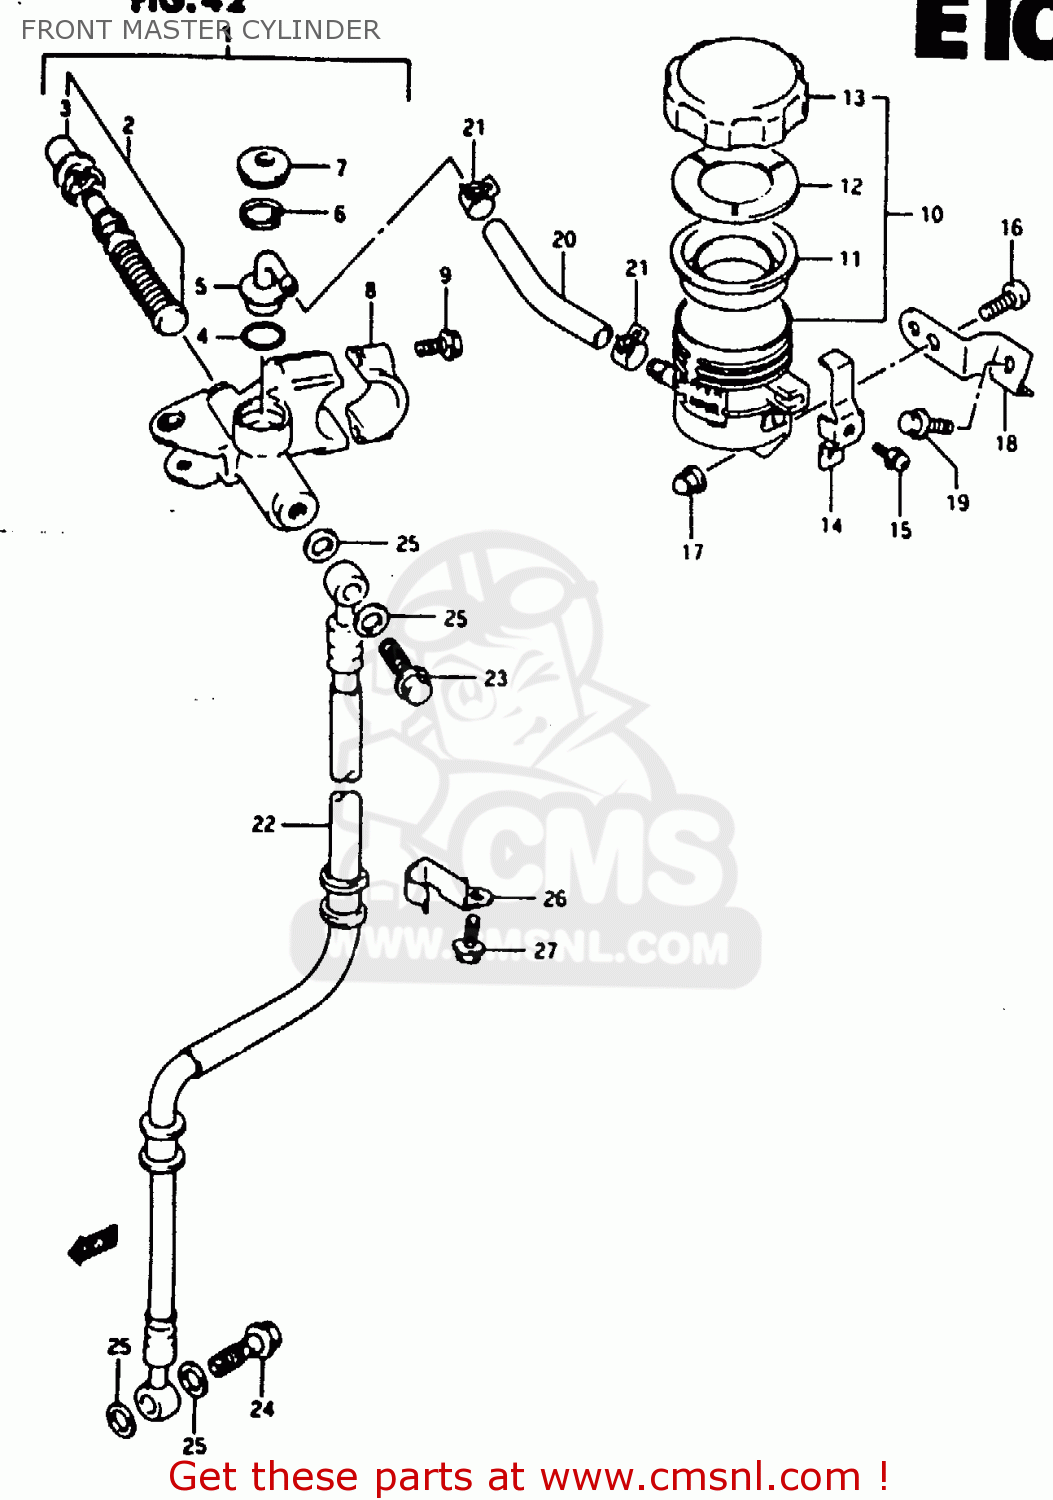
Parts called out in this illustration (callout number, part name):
1	CYLINDER ASSY,FR MASTER
2	PISTON/CUP SET
3	BOOT
4	O RING
5	CONNECTOR
6	CIRCLIP
7	COVER,DUST
8	HOLDER
9	BOLT(6X25)
10	TANK ASSY,RESERVOIR
11	DIAPHRAGM
12	PLATE,DIAPHRAGM
13	CAP
14	PLATE,RESERVOIR TANK CAP
15	SCREW
16	SCREW 6X12
17	NUT
18	BRACKET,FR RESERVOIR TANK
19	BOLT
20	HOSE,FR RESERVOIR TANK
21	CLAMP,RESERVOIR TANK FR
22	HOSE,FR BRAKE
23	BOLT UNION
24	BOLT UNION
25	WASHER(10X15X1.5)
26	CLAMP,FR BRAKE HOSE
27	BOLT
